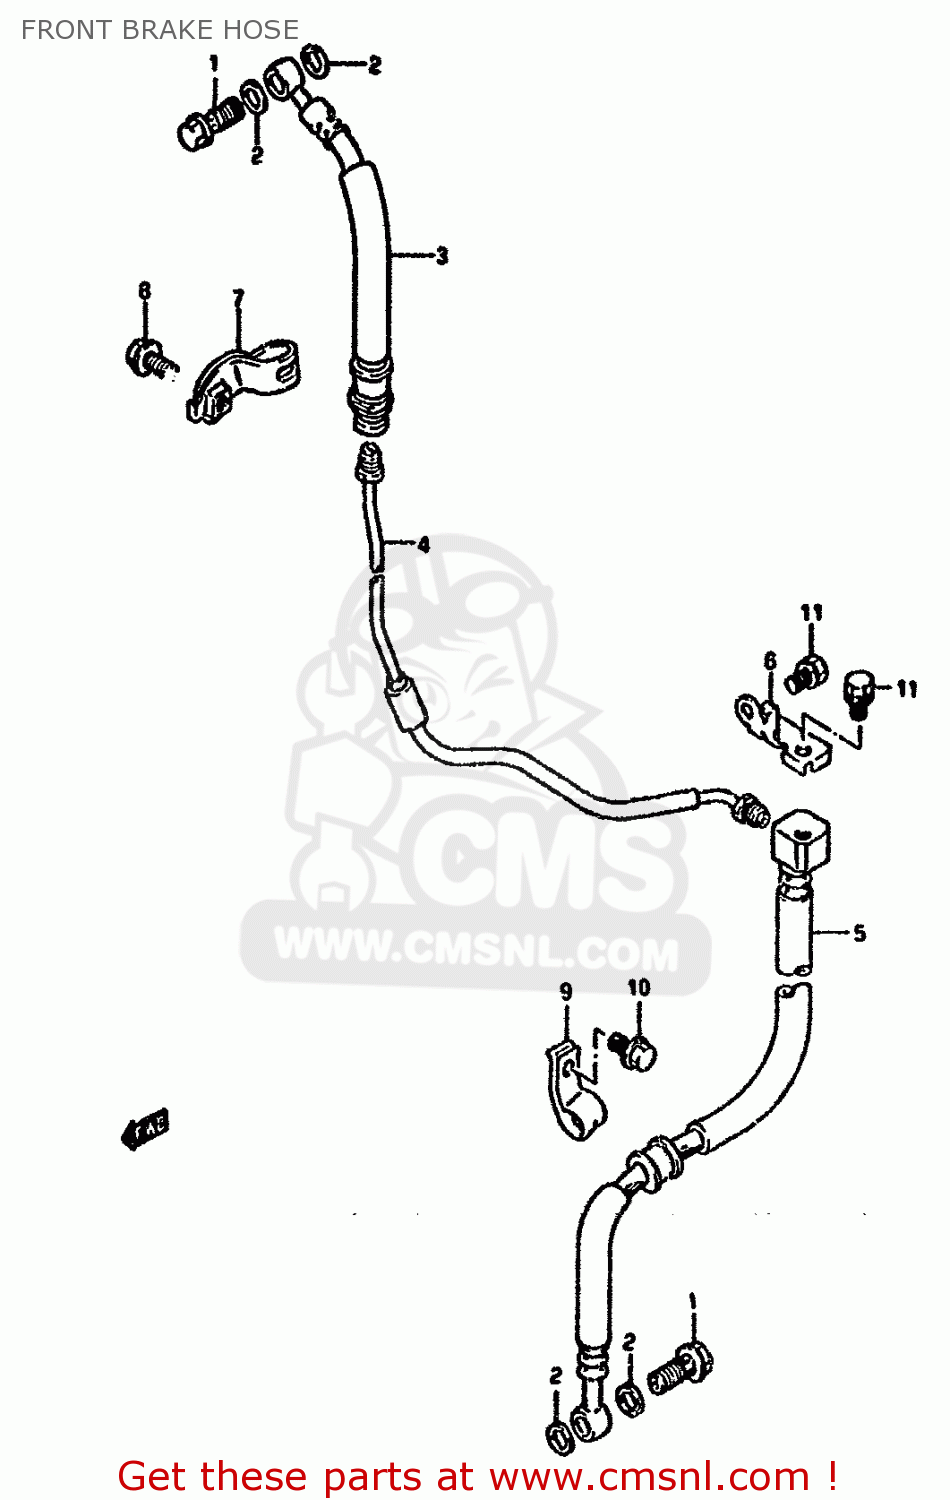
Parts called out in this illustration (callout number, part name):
1	BOLT UNION
2	WASHER(10X15X1.5)
3	HOSE COMP,FRONT BRAKE
4	PIPE,FRONT BRAKE
5	HOSE COMP,FRONT BRAKE
6	BRACKET,FRONT BRAKE HOSE
7	CLAMP COMP,FRONT BRAKE HOLDER
8	BOLT
9	CLAMP,FR BRAKE HOSE NO.2
10	BOLT
11	BOLT
